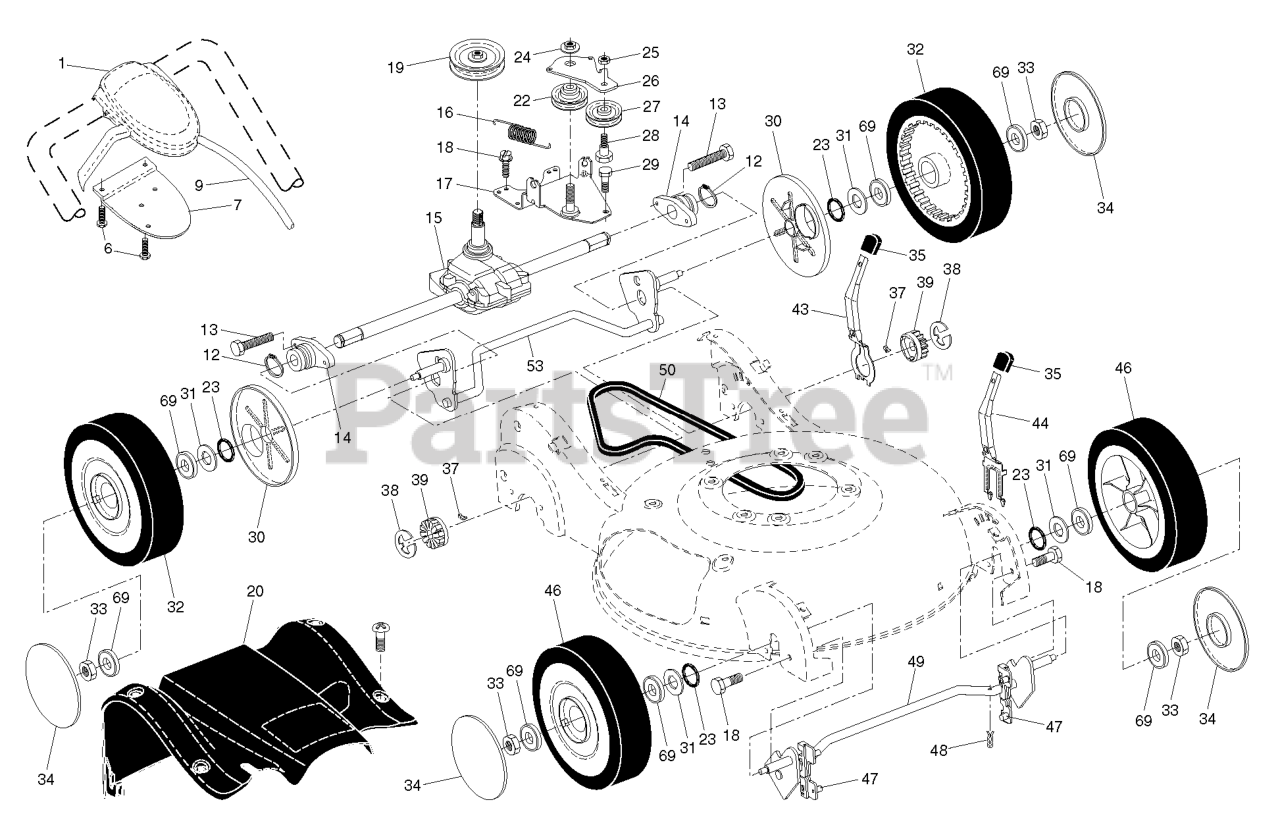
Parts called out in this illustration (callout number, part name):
1	Drive Control Assembly, Complete
6	SCREW, PHILLIPS HEAD 10 X 5/8
7	BRACKET.DRIVE.CONTROL.MOUNT.BL
9	ASM.CABLE.
11	WASHER
12	RETAINING RING (2 2)(3 2)
13	SCREW.1/4-20X21/4.HEX.
14	BEARING / AXLE SUPPORT
15	TRANSMISSION.21.HV.RWGD.AW/EZ
17	BRACKET, GEAR CASE / DRIVE
19	RP PULLEY.DRIVE.EZ
20	COVER.DR.ASM.408006X418.CE
22	PULLEY.IDLER.V-BELT
23	O-RING..070X.487.NEOPRENE
24	NUT.HEX.FLANGE.3/8-16.LOCKNUT
25	NUT.CENTERLOCK.5/16-
26	ARM.IDLER.BZP
27	IDLER PULLEY
28	SHOULDER BOLT
29	SCREW 14-20 X 5/8
30	DUST COVER, WHEEL
31	WASHER.FLAT.1/2
32	WHEEL.9X2.25.LP.TIGER.BLACK
33	NUT.HEX.FLANGE.3/8-16.LO(3 2)
34	HUBCAP.WHEEL.5.SPOKE.SILVER
35	KNOB.SELECTOR.SPRING.BLACK(3 2
37	PAWL, DRIVE
38	E-RING 7/16 RE
39	PINION.14.TEETH.FGD
43	LEVER, SELECTOR, HEIGHT, REAR
44	LEVER, SELECTOR, HEIGHT, FRONT
46	WHEEL.9X2.25.LP.TIGER.BLK
47	BUSHING.FRONT.TORQUE.SHAFT
48	SPRING RETAINER
49	SHAFT FRONT
50	BELT, DRIVE
53	SHAFT.ASM.REAR.TORQUE.HV.BZP
69	BEARING.8".WHEEL
